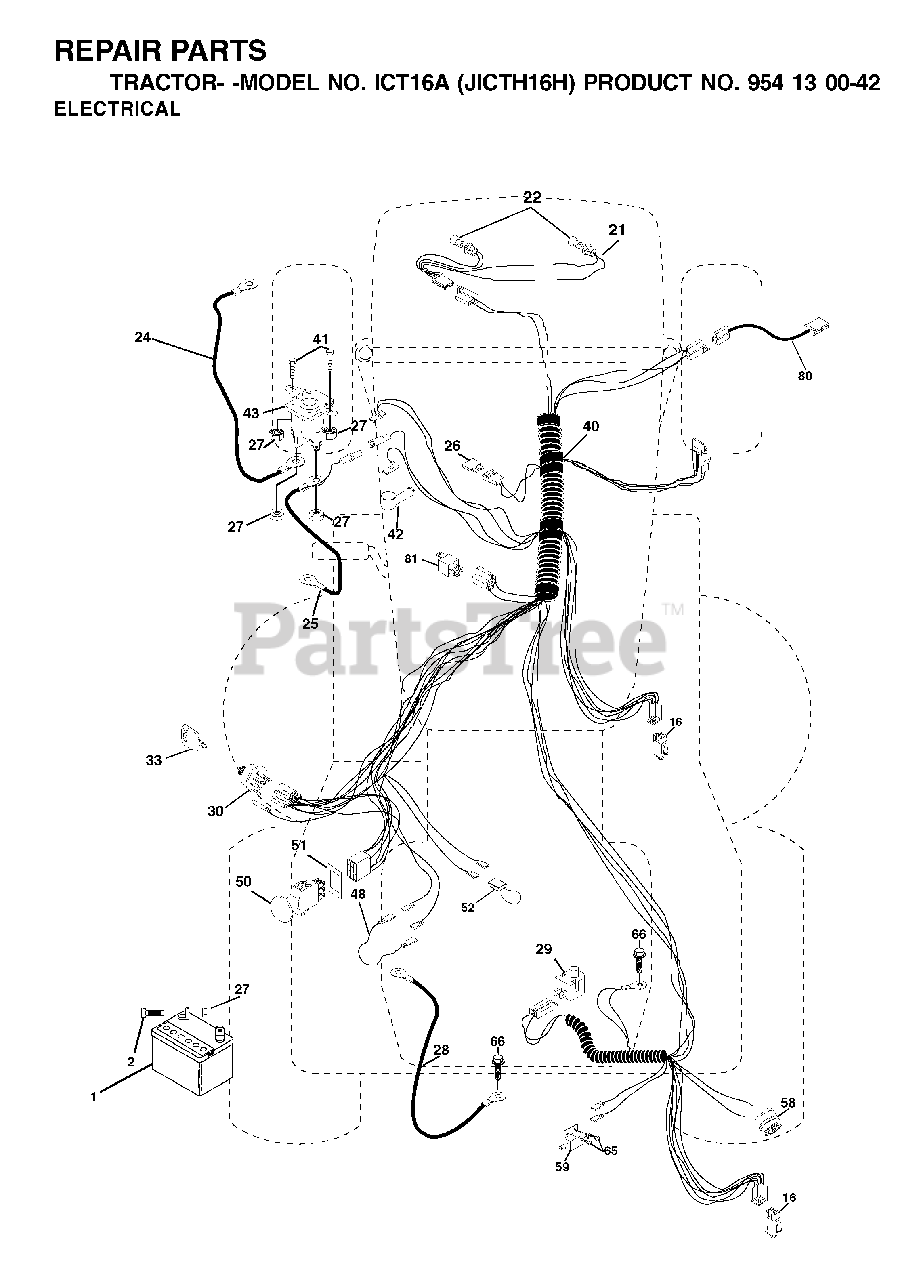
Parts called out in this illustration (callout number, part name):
1	BATTERY 12 VOLT 25 AMP
16	SWITCH INTERLOCK
21	HARNESS.W/LIGHT SOCKET
22	LIGHTBULB
24	BATTERY CABLE GT
25	CABLE BATTERY
26	FUSE 20AMP
27	NUT
28	CABLE GROUND
29	PLUNGER SWITCH (COLOR:OLIVE)
30	IGNITION SWITCH
33	KEY MLD GEN DELTA
40	HARNESS IGN
42	TERMINAL COVER
43	SOLENOID
50	PTO SWITCH
51	RETAINING RING
52	WIRE PROTECTION LOOP
58	BUZZER
80	HARNESS, CLUTCH
81	RELAY.ASSY.T
